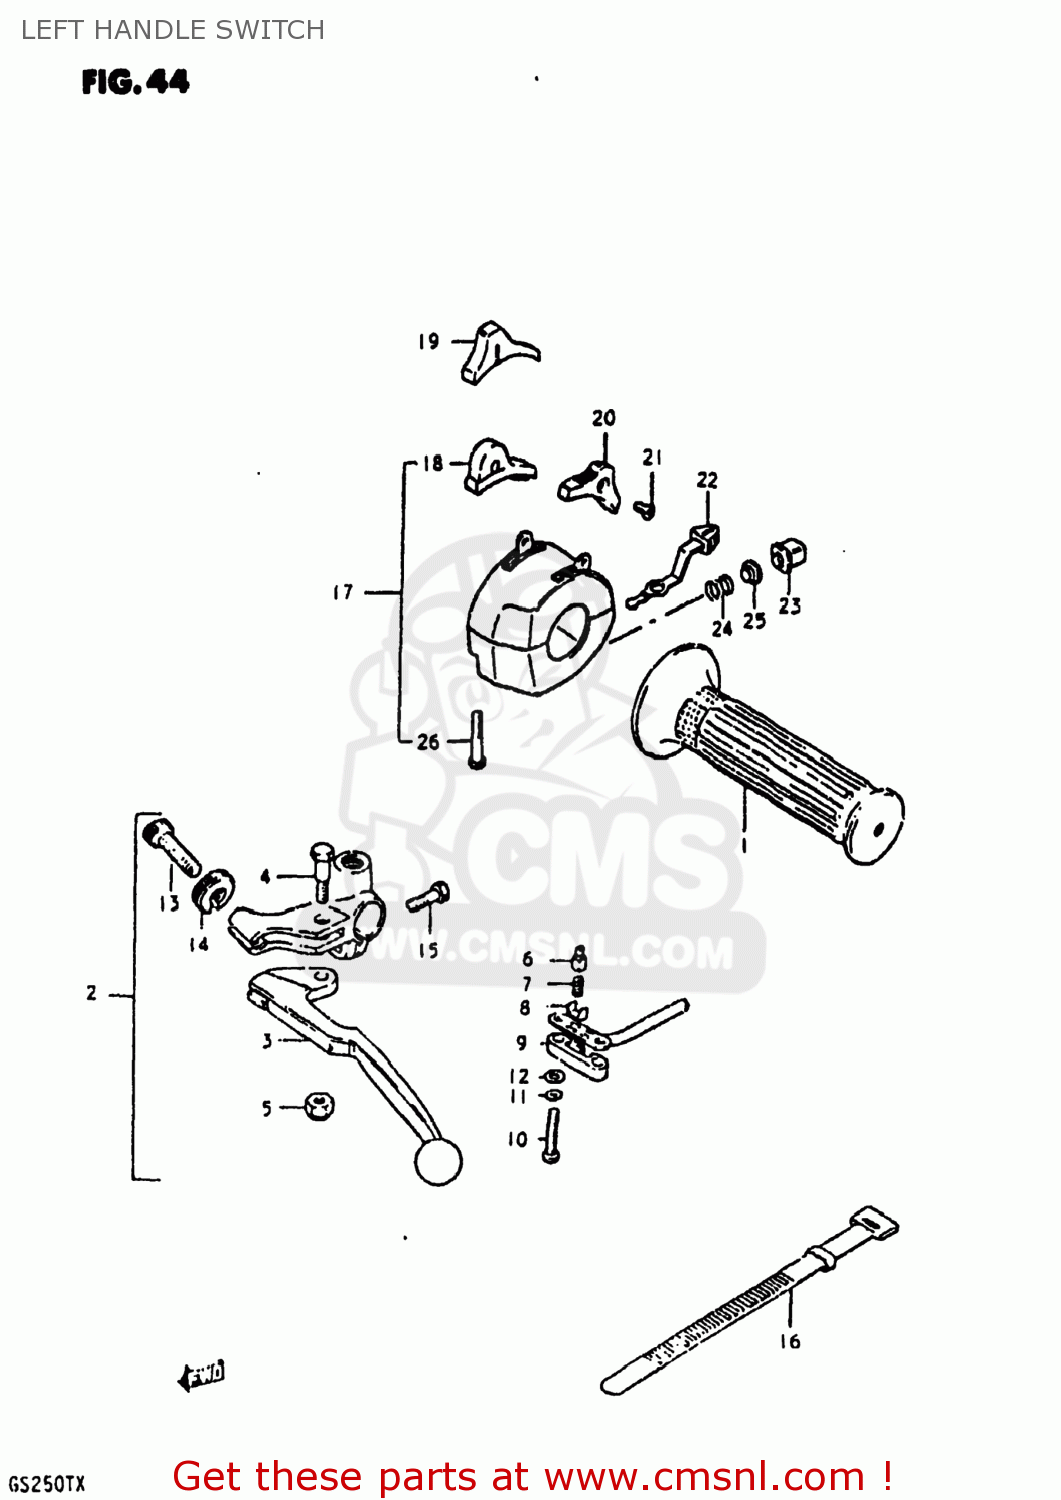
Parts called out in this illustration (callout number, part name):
1	GRIP,LEFT
2	LEVER ASSEMBLY
3	LEVER,CLUTCH
4	BOLT,LEVER
5	NUT 6MM
6	HOLDER
7	SPRING
8	PLATE
9	COVER,FR BK TERMINAL BASE
10	SCREW
11	LOCK WASHER
12	WASHER
13	ADJUSTER,CABLE
14	NUT,CABLE ADJUSTER
15	BOLT,CLUTCH LEVER HOLDER
16	CLAMP(L:120)
17	SWITCH ASSY,HANDLE,L
18	KNOB,STOP
19	KNOB,LIGHTING SWITCH
20	KNOB,DIMMER SWITCH
21	SCREW
22	KNOB,TURNSIGNAL
23	BUTTON,HORN
24	SPRING
25	CONTACT
26	SCREW
